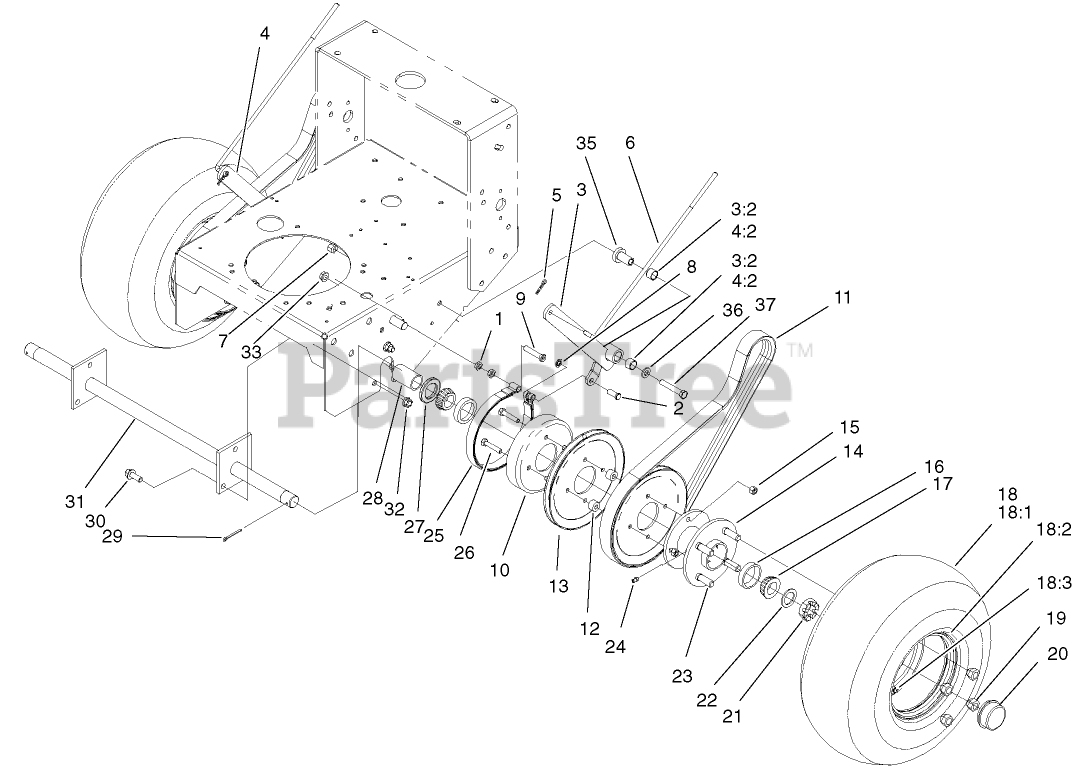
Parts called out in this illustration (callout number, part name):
1	NUT-JAM
2	PIN-CLEVIS
3	LEVER ASM-LH
3:2	SLEEVE-BUSHING
4	LEVER ASM-RH
4:2	SLEEVE-BUSHING
5	PIN-COTTER
6	LINKAGE-BRAKE
7	NUT-LOCK, NI
8	RING-RETAINING, EXTERNAL
10	DRUM-BRAKE
11	BELT-DRIVE, TRACTION
12	SPACER-PULLEY
13	PULLEY-WHEEL
14	HUB/WHEEL ASM
15	NUT-LOCK, NI
16	BEARING-CUP, TAPERED
17	BEARING-CONE, TAPERED
18	WHEEL AND TIRE ASM
18:3	STEM-VALVE
19	NUT-LUG
20	CAP-DUST
21	NUT-SHH
22	WASHER-SPACER
23	STUD-WHEEL
24	FITTING-GREASE
25	BAND-BRAKE
26	SCREW-HH
27	SEAL-GREASE
28	SPACER-WHEEL
29	PIN-COTTER
30	SCREW-HHF
31	AXLE ASM
32	NUT-HF
33	NUT-HHF, WHIZ
35	BUSHING-PIVOT
36	WASHER-FLAT
37	SCREW-HH
